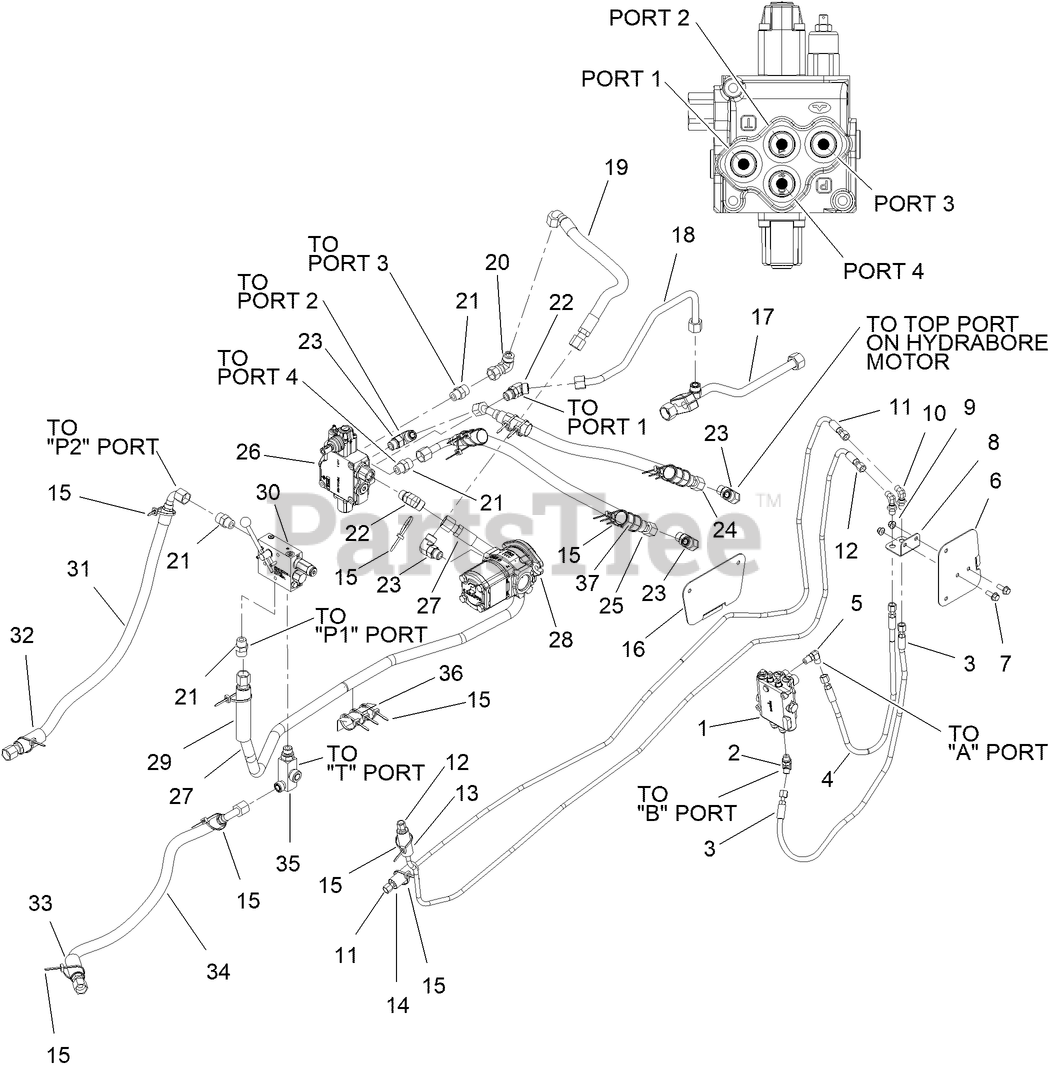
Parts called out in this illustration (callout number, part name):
1	HYD STEERING VALVE ASM
3	HOSE (04OFX-32"-3000)
4	HOSE (04OFX-27"-3000)
5	FITTING-ELBOW, 90 DEG
6	COVER-SELECTOR (TORO RED)
7	SCREW-HHF
8	PLATE-BULKHEAD
9	NUT-HF, NI
10	BK CONNECTOR (04O-04O90BK)
11	HOSE (04OFX-82"-3000)
12	HOSE (04OFX-92.5"-3000)
13	ABRASION SLEEVE (1.00" X 92")
14	ABRASION SLEEVE (1.00" X 82")
15	TIE-CABLE
16	COVER-TRENCHER (TORO RED)
17	HARDLINE (-12 RETURN TO COOLER)
18	HARDLINE (HYDRABORE TO RETURN)
19	HOSE (10OFX90S-18"-3000)
20	FITTING-HYD-90
21	CONNECTOR (10S-10O)
22	CONNECTOR (10S-10O45)
23	CONNECTOR (10S-10O90)
24	HOSE (10OFX45-53"-3000)
25	HOSE (10OFX90L-54"-3000)
26	HYDRO VALVE ASM
27	HOSE (10OFX-64"-3000)
28	PUMP TANDEM (1.29/.44 CIR)
29	ABRASION SLEEVE (1.25" X 64")
30	VALVE-CONTROL, VIBE PLOW
31	HOSE (10OFX90S-36"-3000)
32	ABRASION SLEEVE (1.25" X 37")
33	ABRASION SLEEVE (1.25" X 33")
34	HOSE (10OFX90S-33"-3000)
35	CONNECTOR (10S-10O-12O)
36	PROTECTOR-HOSE
37	PROTECTOR-HOSE
